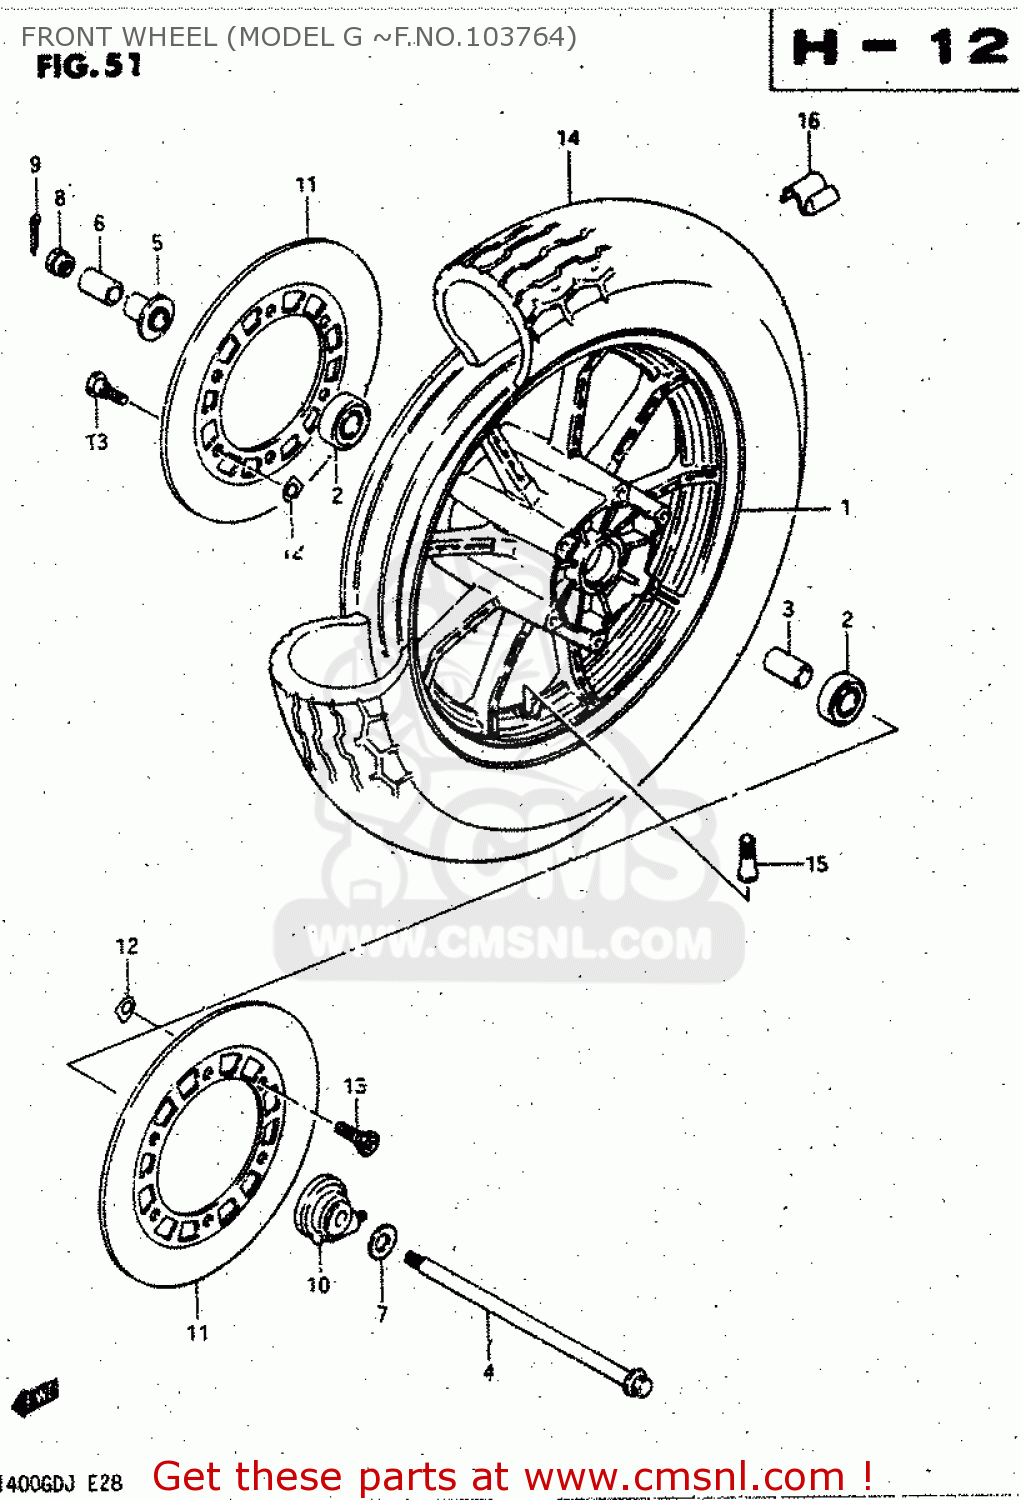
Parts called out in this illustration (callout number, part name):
1	WHEEL,FRONT
2	BEARING
3	SPACER
4	AXLE,FRONT
5	SPACER,FR HUB BEARING,R
6	SPACER,FR AXLE,R
7	WASHER
8	NUT (12MM)
9	PIN,FRONT AXLE
10	BOX ASSY,SPEEDOMETER GEAR
11	DISC,FRONT BRAKE
12	SHIM,BRAKE DISC
13	BOLT(8X25.5)
14	TIRE,FRONT
15	VALVE,TIRE
16	BALANCER,WHEEL
